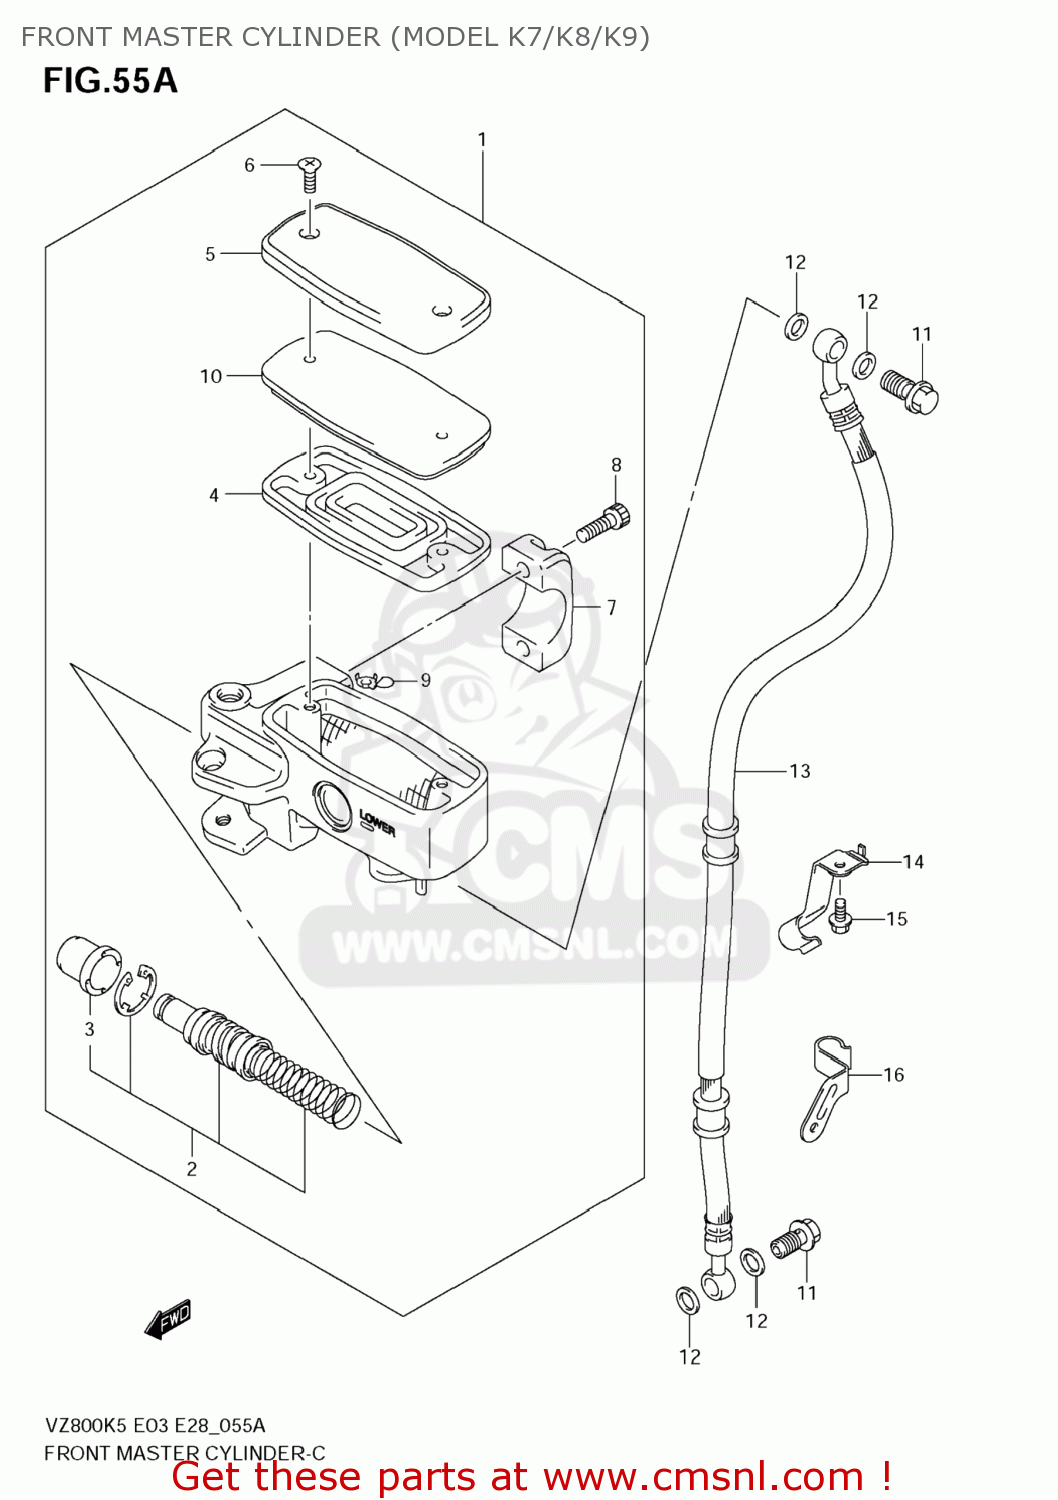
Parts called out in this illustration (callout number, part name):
1	CYLINDER ASSY,FR MASTER
2	PISTON/CUP SET
3	BOOT
4	DIAPHRAGM
5	CAP
6	SCREW
7	HOLDER
8	BOLT
9	PROTECTOR
10	PLATE,DIAPHRAGM
11	BOLT UNION
12	WASHER(10X15X1.5)
13	HOSE,FR BRAKE
14	CLAMP,FR BRAKE HOSE UPR
15	BOLT
16	CLAMP,FR BRAKE HOSE
